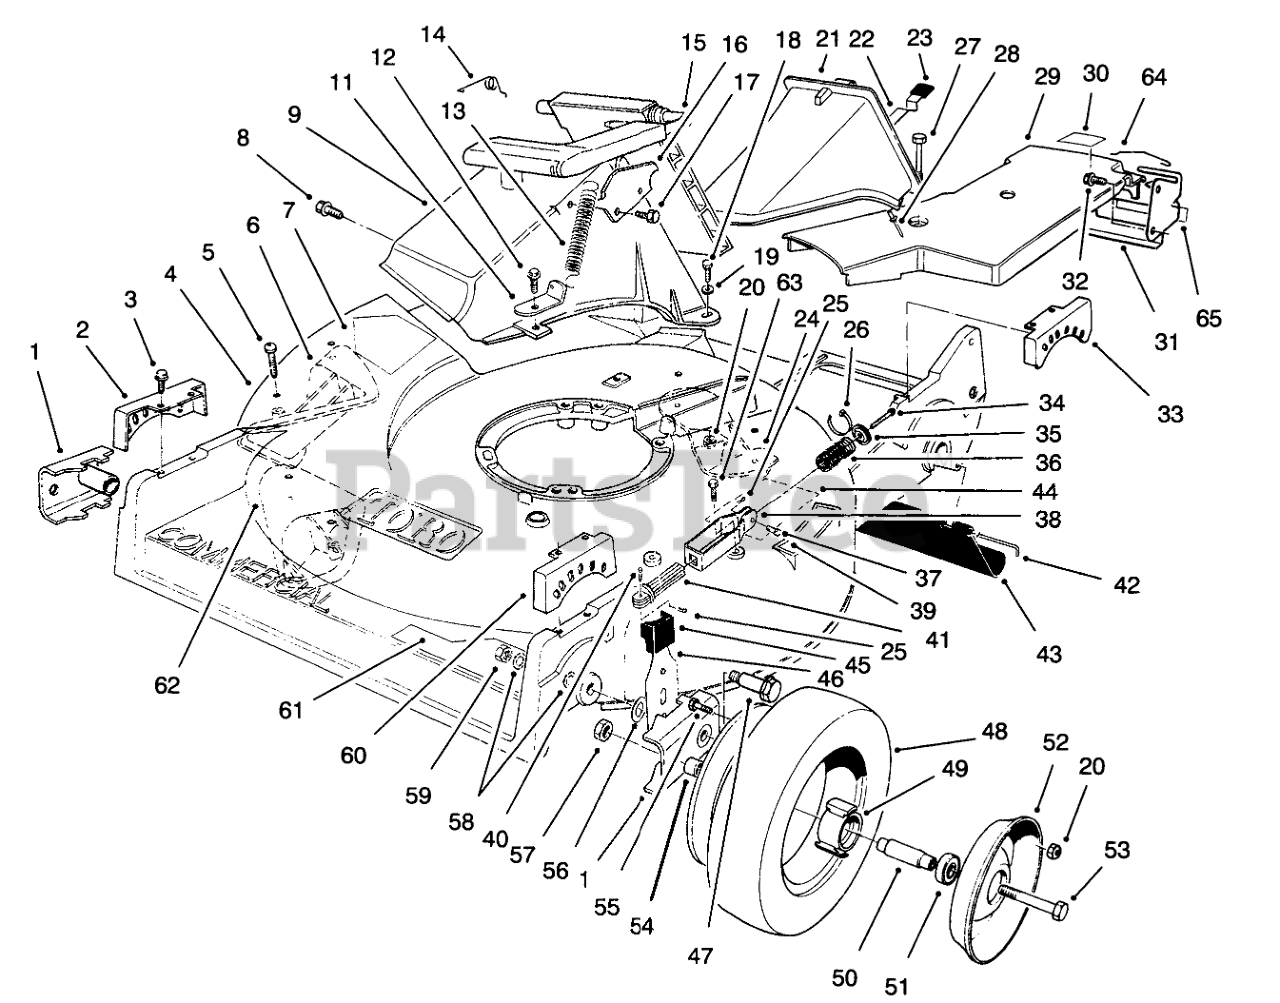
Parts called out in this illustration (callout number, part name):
1	ARM-PIVOT, FRONT
2	QUADRANT-FRONT, RH
3	SCREW-HWHTF
4	Housing-Commercial (Incl. Ref. #5-7, 24, 44, & 62 pg. 1-2) (Incl. Ref. #28 pg. 4)
5	SCREW-PPH
6	KICKER-RH
7	DECAL-DANGER
8	SCREW AND WASHER ASM
9	DISCHARGE TUNNEL
9	TUNNEL-DISCHARGE
11	BRACKET-SPRING
12	SCREW-HWH
13	SPRING-DOOR
14	RETAINER-DOOR
15	DOOR ASSEMBLY
15	DISCHARGE DOOR ASM
16	DOOR LATCH PLATE
16	LATCH-PLATE
17	SCREW-PLASTITE
18	SCREW-HH
19	WASHER-FLAT
20	NUT-LOCK, NI
21	Plug-Discharge (Incl. Ref. #22, 23, & 28)
22	LATCH-PLUG, DISCHARGE
23	GRIP-LATCH
24	KICKER-REAR
25	PIN-COTTER
26	TIE-CABLE
27	SCREW-HHFTF
28	RIVET-HEAD, FLAT
29	BELT COVER (MACHINED)
30	LABEL-GREASE
31	BRACKET-ADJUSTMENT, TRACTION
32	SCREW-HWHTF
33	QUADRANT-REAR, LH
34	SCREW-HWHTF
35	RETAINER-SPRING
36	SPRING
37	PIN-CABLE
38	Bracket-Spring
39	STEP PAD DECAL
40	PIN-SPRING
41	GUIDE-SPRING
42	ROD-SHIELD
43	SHIELD-TRAILING
44	DECAL - DANGER, COVERS
45	KNOB-ARM
46	FRONT SPRING ARM ASM
47	BOLT-WHEEL
49	HUB-BEARING
50	SPACER-BEARING
51	BEARING-WHEEL
52	Wheel-Half
53	SCREW-HH
54	SPACER-WHEEL
55	SCREW-HH
56	WASHER-THRUST
57	NUT-LOCK, CONE
58	WASHER
59	NUT-LOCK
60	QUADRANT-FRONT, LH
61	DECAL - RECYCLER
62	KICKER-FRONT
63	SCREW-HH
64	RETAINER-CABLE
65	DECAL-POSITION, GEAR
